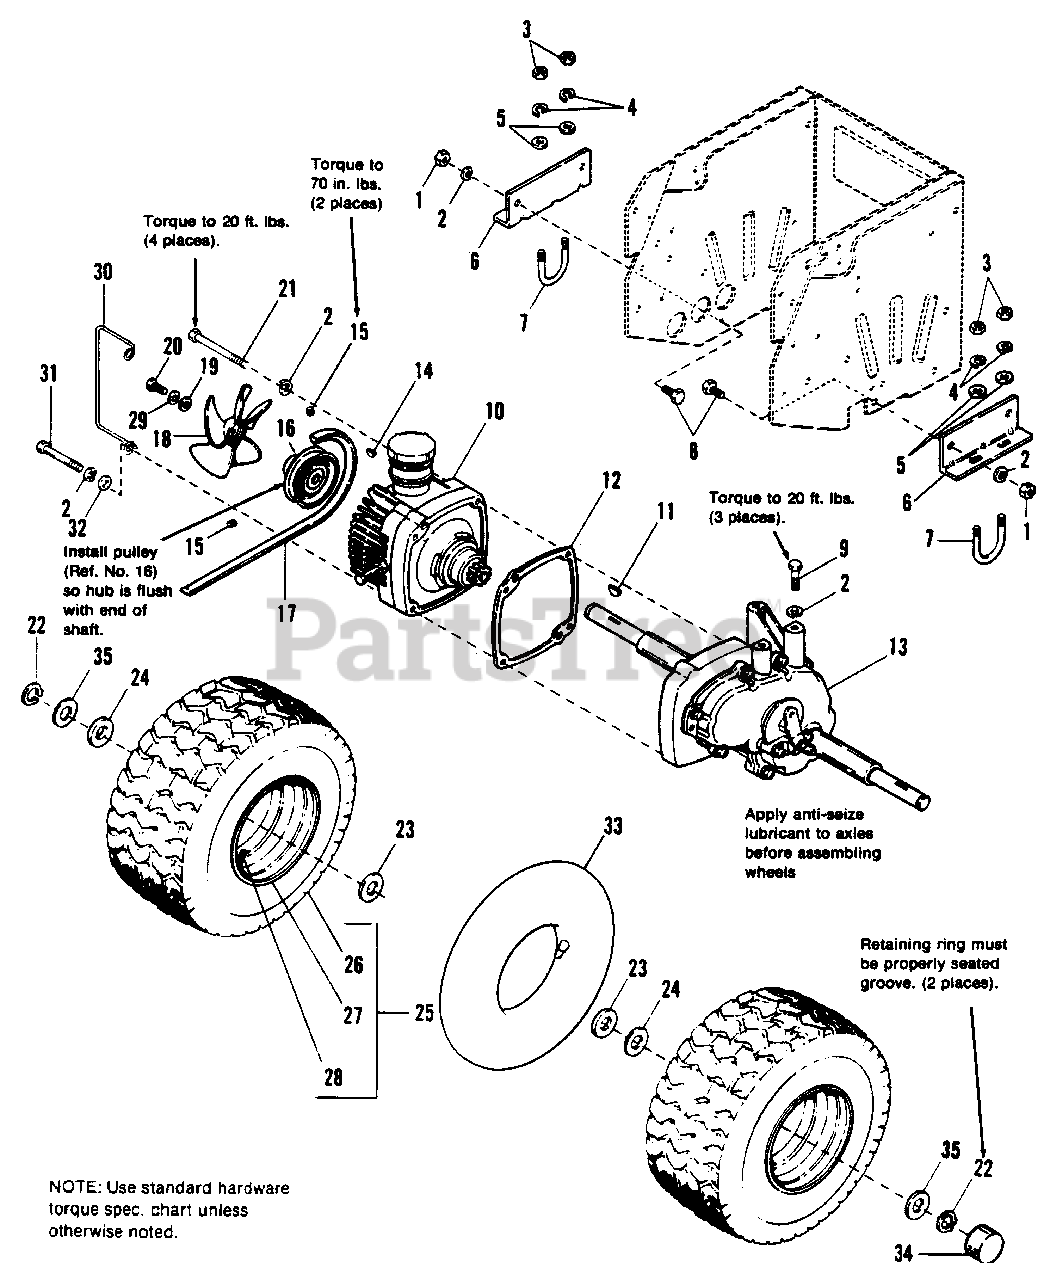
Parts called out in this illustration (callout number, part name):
1	NUT, Hex, 3/8-16
2	LOCKWASHER, 3/8
3	NUT, Hex, 5/16-18
4	LOCKWASHER, 5/16
5	WASHER, 5/16
6	SUPPORT, Transmission
7	"U" BOLT, Axle
8	CAPSCREW, Hex, 3/8-16 x 3/4
9	CAPSCREW, Hex, 3/8-16 x 1
10	TRANSMISSION, Hydrostatic (See pages 16 & 17 for parts list)
11	KEY, Woodruff, #18, 1/4 x 1-1/4
13	GEAR REDUCTION & DIFFERENTIAL ASSY
14	KEY, Woodruff, #3, 1/8 x 1/2
15	SETSCREW, Hex Soc. Cup, 1/4-28
16	PULLEY, Transmission
17	BELT, "V" Drive, Transmission
18	FAN, 7" Diameter
19	WASHER, 1/4
20	CAPSCREW, Hex, 1/4-2 x 1/2
21	CAPSCREW. Hex, 3/8-16 x 3
22	RING, Retainer
23	WASHER, 1 x 1-3/4, Thrust
24	WASHER, Plain, 1 x 1-3/4, Plated
25	WHEEL & TIRE ASSY. (Used on 1690381 & 1690936)
25	WHEEL & TIRE ASSY. (Used on 1690853 & 1690919)
26	TIRE, 20 x 10 x 10 (Used on 1690881 & 1690936)
26	TIRE, 20 x 8 x 10 (Used on 1690853 & 1690919)
27	WHEEL ASSY.
28	VALVE STEM & CAP
29	LOCKWASHER, 1/4
30	BELT STOP
31	CAPSCREW, 3/8-16 x 3-1/4
32	WASHER, 3/8
33	TUBE (For Service Only, See note)
34	CAP, Hub, Threaded
35	WASHER, 1 x 1-7/8
